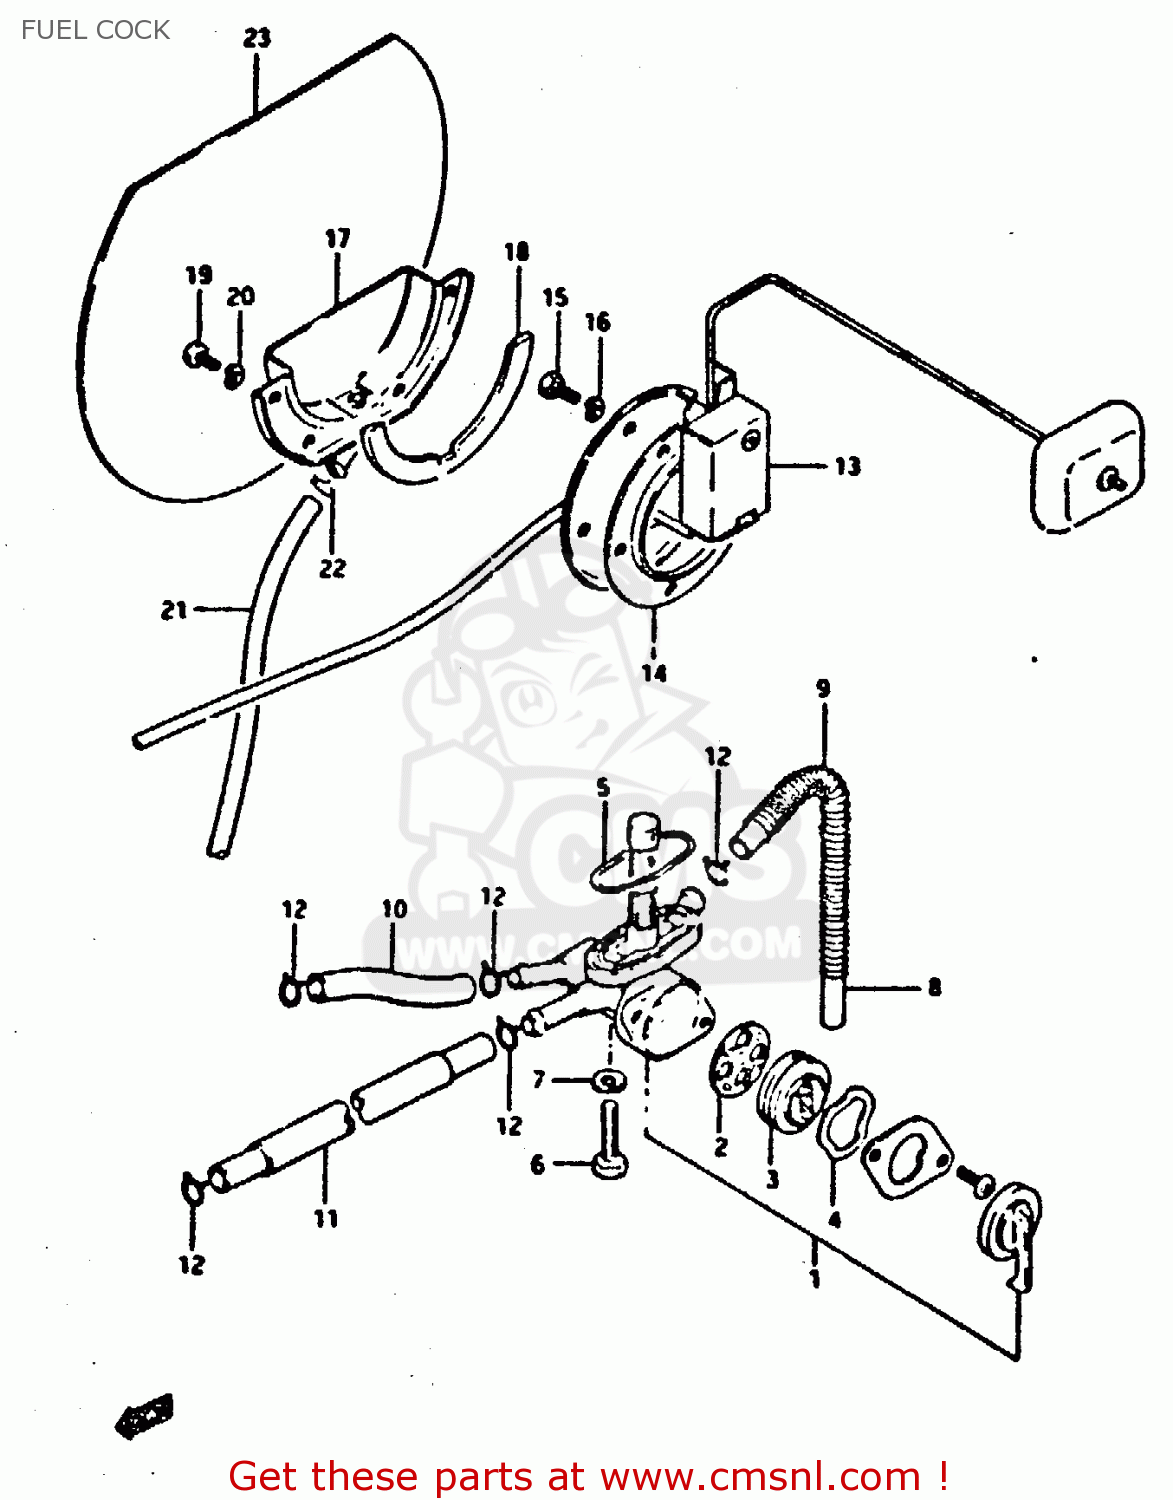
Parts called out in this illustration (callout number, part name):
1	COCK ASSEMBLY,FUEL
2	GASKET,FUEL COCK
3	VALVE,FUEL COCK
4	WASHER, LEVER
5	GASKET,FUEL COCK
6	BOLT(6X20)
7	GASKET
8	HOSE
9	SPRING
10	HOSE
11	HOSE
12	CLAMP
13	GAUGE ASSEMBLY,FUEL LEVEL
14	GASKET,FUEL LEVEL GAUGE (NAS)
15	BOLT
16	LOCK WASHER
17	PLATE,FUEL DRAIN
18	GASKET (NAS)
19	SCREW
20	LOCK WASHER
21	HOSE,FUEL
22	CLIP
23	PROTECTOR, FUEL LEVEL GAUGE
